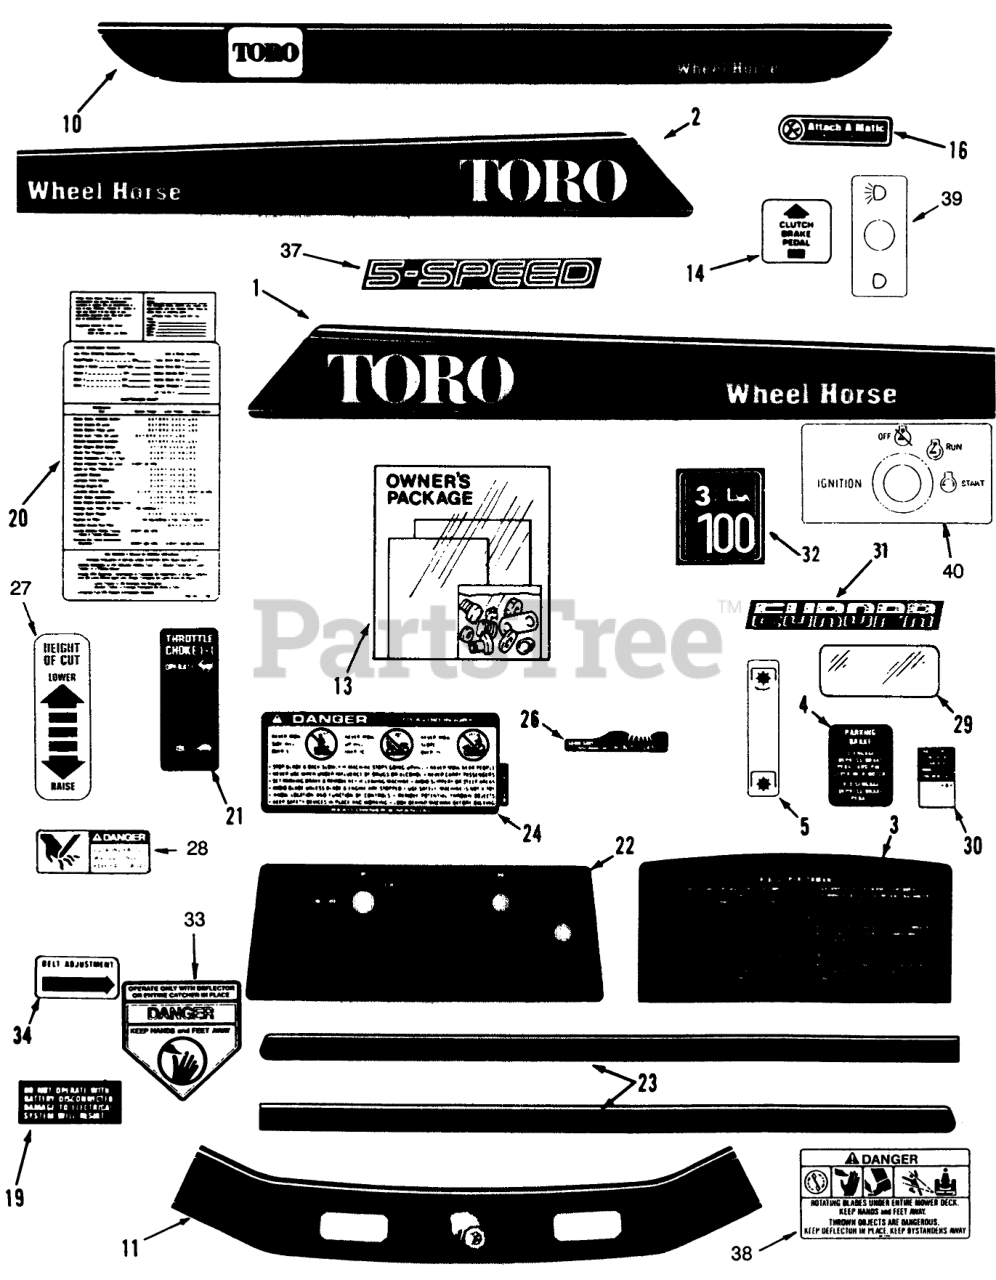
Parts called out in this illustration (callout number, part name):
1	DECAL-HOOD 2125SB RH
2	DECAL-HOOD 2125SB LH
3	Decal-Hood Rear
4	Decal-Parking Brake
5	DECAL-PTO
10	DECAL-FENDER
11	DECAL-FRONT HOOD
13	New Tractor Loose Parts Package
14	DECAL CLUTCH & BRAKE
16	Decal-Attach-A-Matic
19	DECAL ELECT SYSTEM
20	MAINTENANCE-DECAL
21	DECAL-THROTTLE
22	DECAL-BACK PLATE
23	DECAL HOOD STRIPE RH
24	DECAL-DANGER
26	DECAL-SHIFT 5-SPEED
27	DECAL-HOC
28	Danger Decal
29	DECAL-OVERLAY
30	DECAL-PTO BELT ADJ
31	DECAL-EUROPA
32	DECAL-EUROPE
33	DECAL-DANGER
34	DECAL-BELT ADJUST
37	DECAL-MODEL 5-SPEED
38	DECAL-DANGER, THROWN OBJECT
39	DECAL-LIGHTS
40	DECAL-IGNITION
